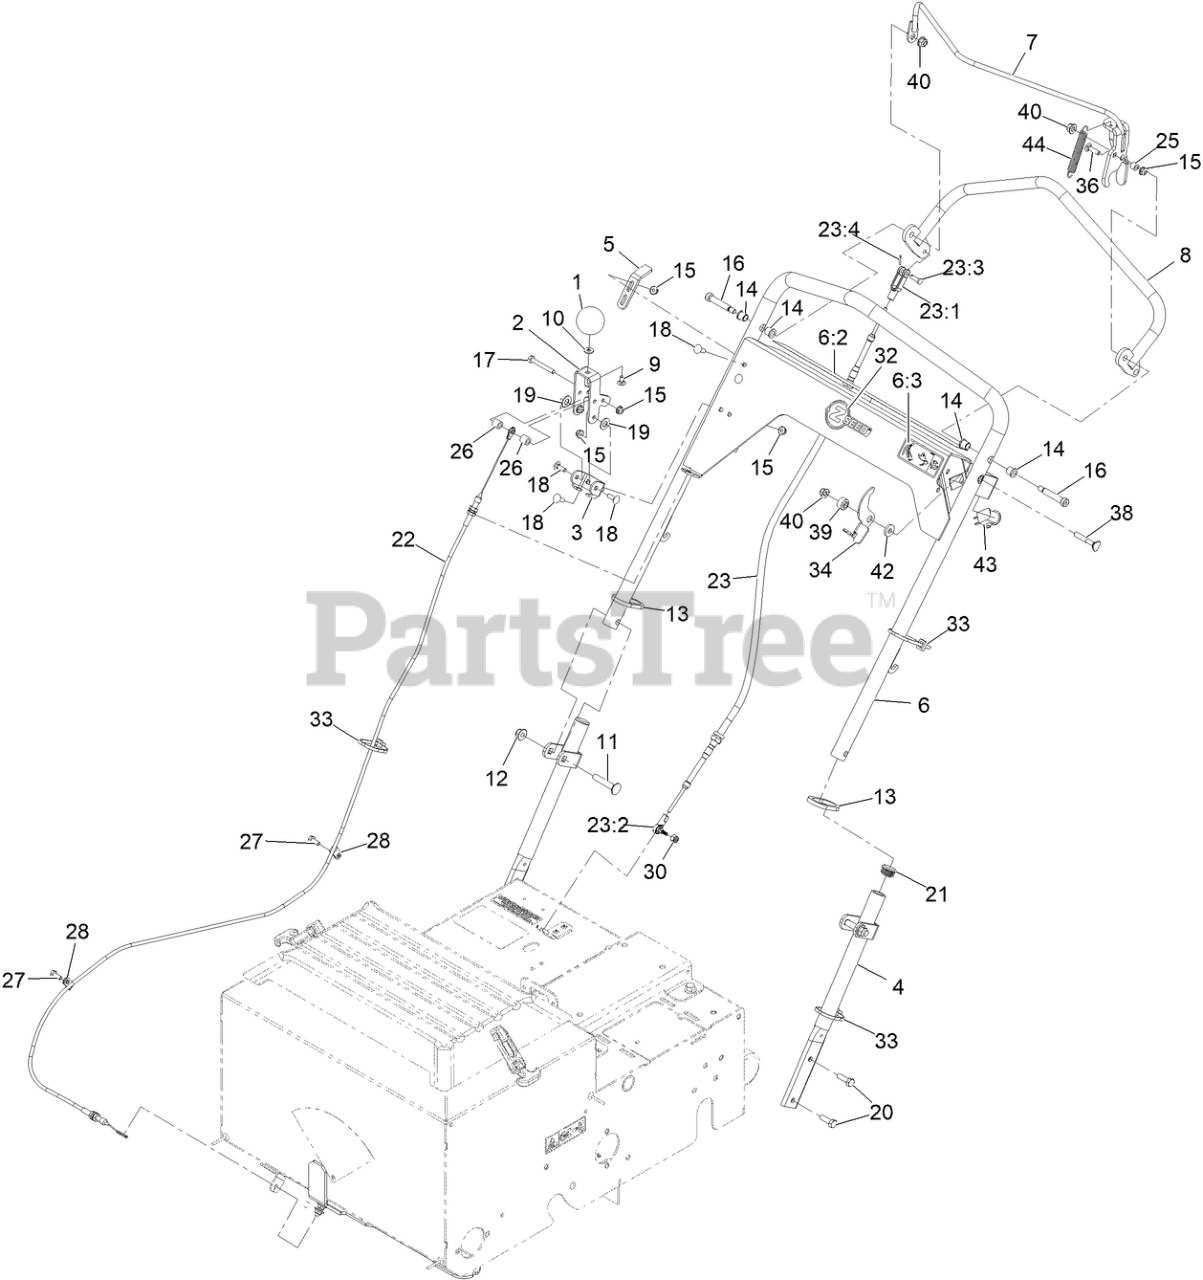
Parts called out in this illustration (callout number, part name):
1	KNOB-RATE, FLOW
2	LEVER-ADJUST, FLOW
3	BRACKET-ADJUST, FLOW
4	HANDLE-LOWER
5	BRACKET-ADJUST, DRIVE
6:2	DECAL-CONTROL PANEL, SEED
6:3	DECAL-SAFETY LATCH
7	BAIL-CLUTCH
8	DRIVE HANDLE WA
9	SCREW-CARR
10	WASHER-FLAT
11	SCREW-CARR
12	NUT-HF, NI
13	RING-HANDLE LOCK
14	BEARING
16	SCREW-SHOULDER
17	SCREW-HH
18	BOLT-CARR
19	WASHER-PLAIN
20	SCREW-HH
22	CABLE-FLOW, SEED
23	CABLE-PUSH PULL
23:2	Ball Joint
23:3	Pin-Clevis
23:4	PIN-COTTER
27	SCREW-HH
28	CLAMP-R
30	NUT-LOCK
32	DECAL-Z-SEED LOGO
33	TIE-CABLE
34	LATCH-BAIL
36	SCREW-CARR
39	BUSHING-STEPPED
40	NUT-HF, NI
42	WASHER-FLAT
43	SWITCH-BAIL
